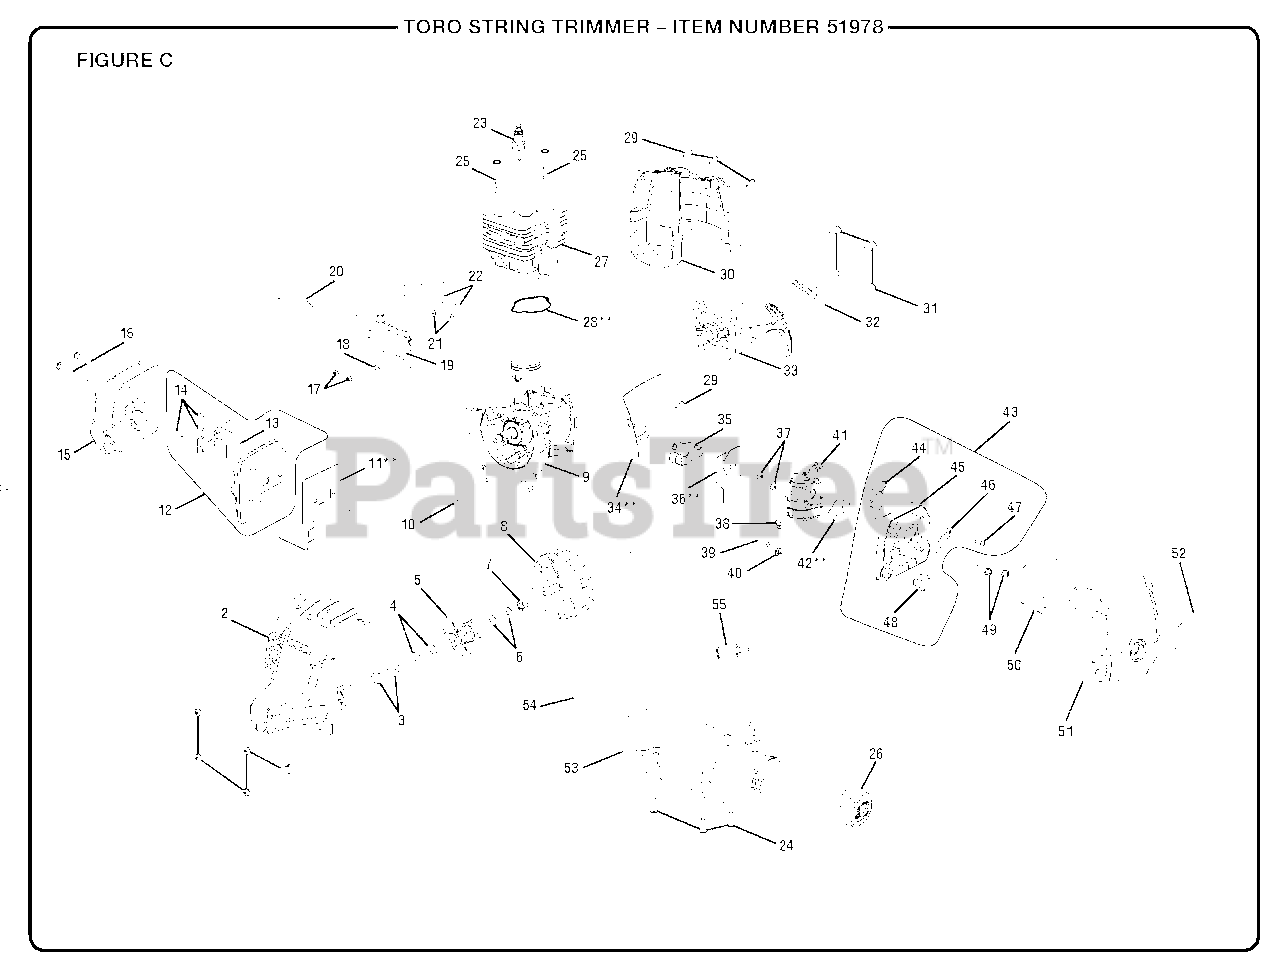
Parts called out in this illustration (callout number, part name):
1	Screw (M5 x 20 mm, T20 Torx Pan Hd.)
2	Front Housing Assembly
3	Clutch Shoulder Bolt (M6 x 22.5 mm, Hex Hd.)
4	Curved Washer
5	Clutch Assembly
6	Washer (ID6 x OD15 x 1.2t)
7	Flywheel Nut
9	Crankcase Assembly
10	Woodruff Key (10 mm x 3 mm)
11	Muffler Gasket
12	Muffler Assembly
13	Screen
14	Screw (6-20 x 1/4 in., T20 Torx Pan Hd. S.T.)
15	Heat Shield
16	Screw (M5 x 50 mm, T25 Torx Soc. Hd.)
17	Screw w/Washer (M4 x 19 mm, T20 Torx Soc. Hd.)
18	Lead Wire (Red)
19	Coil Boot Assembly
20	Lead Wire (Black)
21	Washer (ID4.2 x OD10 x1t)
22	Spacer (Phenolic)
23	Spark Plug (Champion RCJ4)
24	Screw (M5 x 16 mm, T25 Torx Soc. Hd.)
25	Screw (M5 x 22 mm, T25 Torx Soc. Hd.)
26	Fuel Cap Assembly
28	Gasket
29	Screw (M4 x 18 mm, T20 Torx Pan Hd. S.T.)
30	Rear Engine Housing
31	Screw w/Washer (M5 x 16 mm, T25 Torx Soc. Hd.)
32	Logo Label (Rear)
33	Starter Recoil & Starter Cup Assembly
34	Insulator Gasket
35	Heat Dam Insulator
36	Gasket
37	Screw w/Washers (M5 x 34 mm, T25 Torx Pan Hd.)
38	Hose Clip
39	Fuel Line (45 mm)
40	Hose Clip
41	Carburetor Assembly
42	Carburetor Gasket
43	Airbox Base Assembly
44	Choke Lever
45	Airbox Base
46	Choke Plate
47	Screw (M4 x 12 mm, T20 Torx Pan Hd. S.T.)
48	Primer Assembly
49	Screw (M5 x 60 mm, T25 Torx Cap Soc. Hd.)
50	Air Filter
51	Airbox Cover Assembly w/Label
52	Starting Instructions Label
53	Fuel Tank & Cap Assembly
54	Combustion Warning Label
55	Fuel Filter
